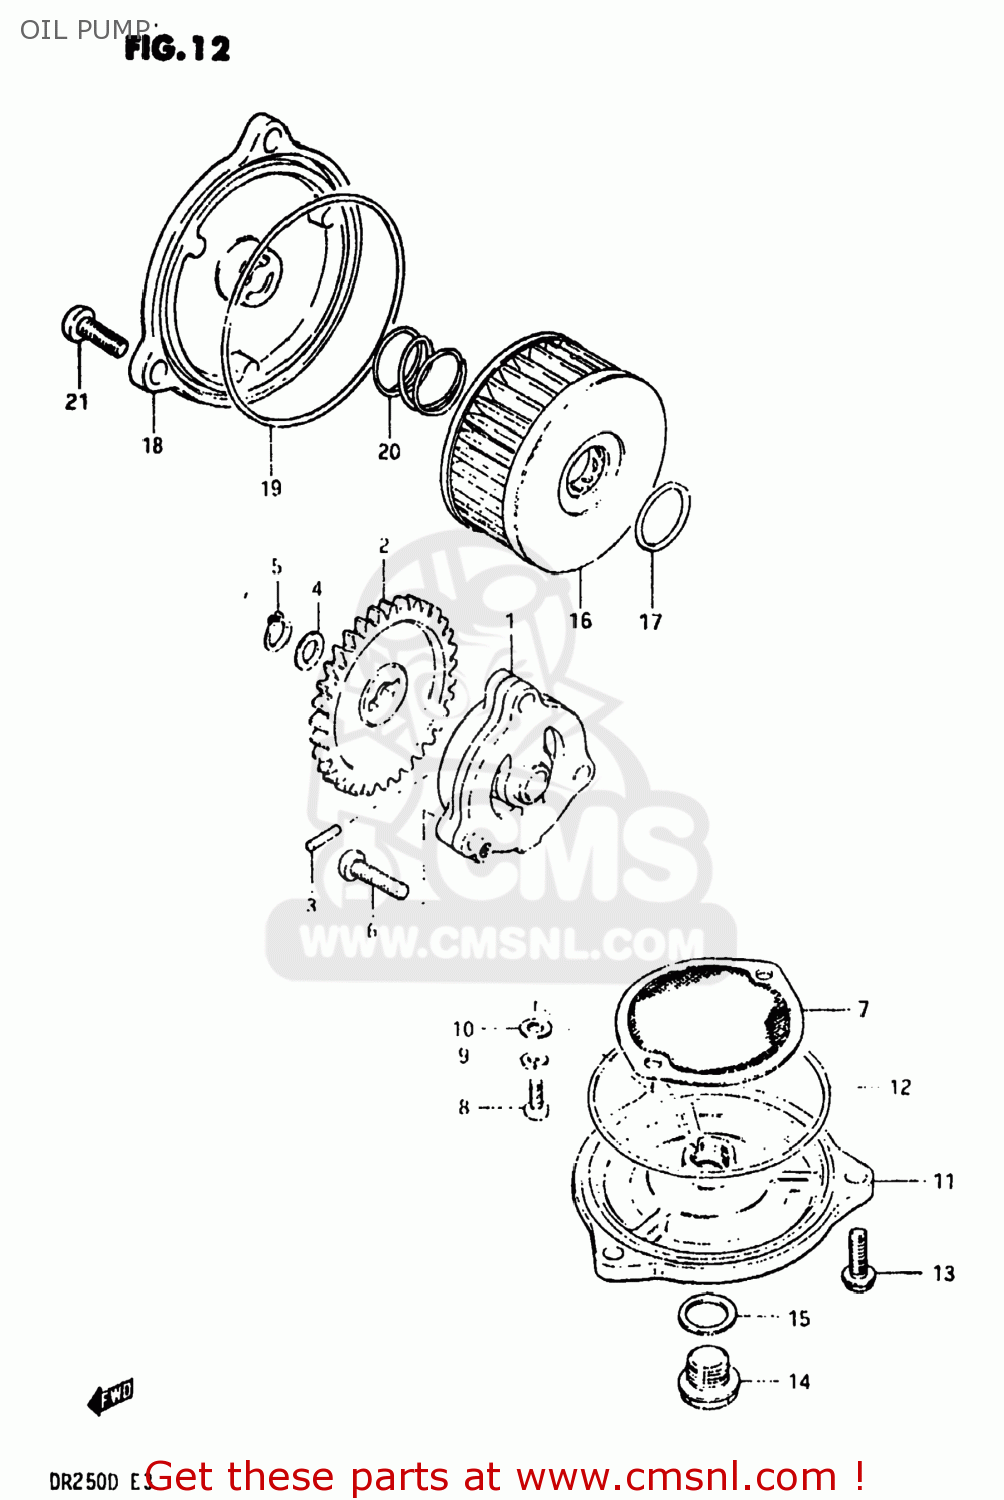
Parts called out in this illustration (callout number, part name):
1	PUMP ASSY,ENGINE OIL
2	GEAR,OIL PUMP DRIVEN(NT:33)
3	PIN(4X15.8)
4	SHIM
5	CIRCLIP
6	SCREW
7	STRAINER,ENGINE OIL
8	SCREW
9	LOCK WASHER
10	WASHER
11	CAP,OIL STRAINER
12	O RING(D:2.4,ID:85)
13	BOLT (6X20)
14	PLUG
15	GASKET(14X19.2X2) (NAS)
16	FILTER ASSY,ENGINE OIL
17	O RING(D:2.4,ID:15.8)
18	CAP,OIL FILTER
19	O RING(D:2.4,ID:73)
20	SPRING
21	SCREW
